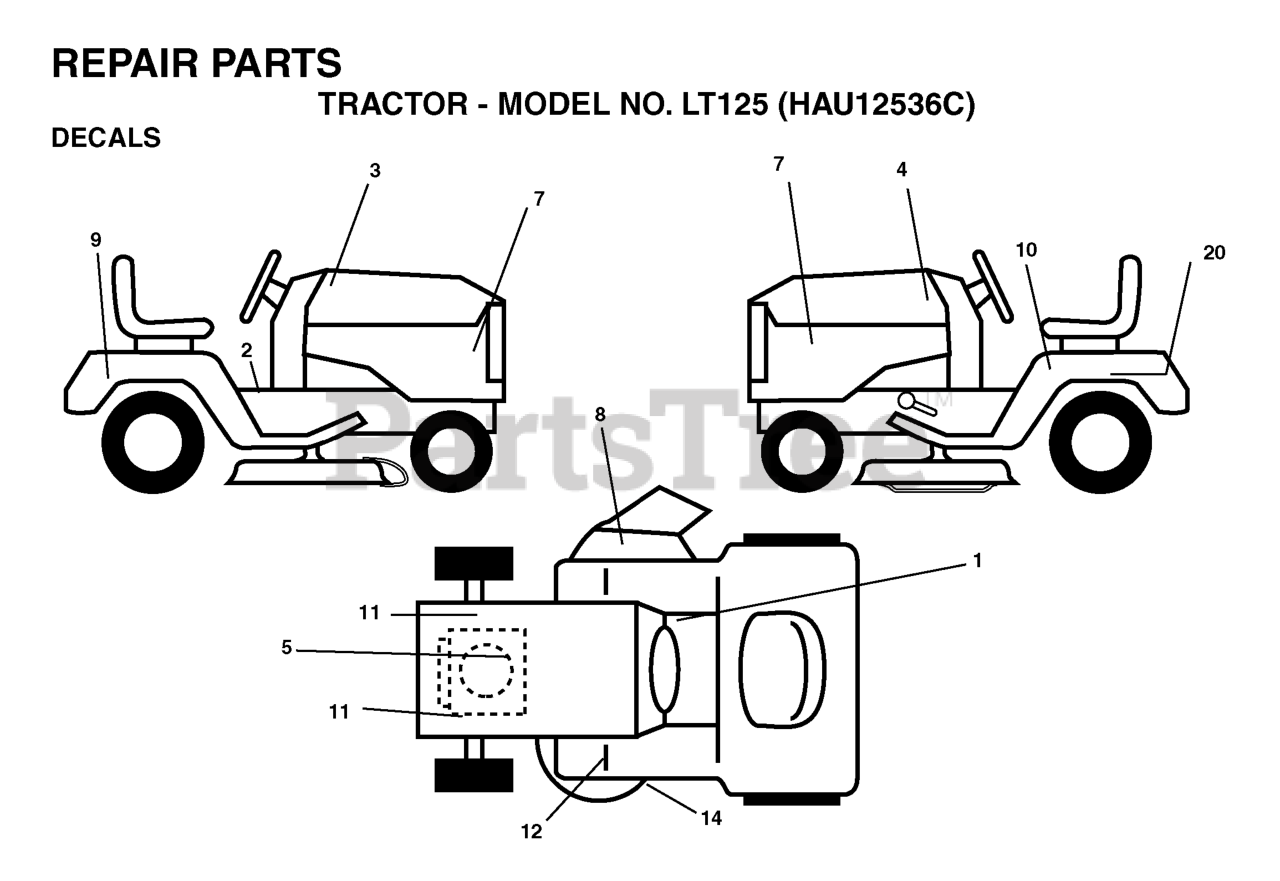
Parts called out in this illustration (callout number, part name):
1	DECAL
2	DECAL PARK BRAKE
7	DECAL PNL SIDE
8	DECAL.INTERNATIONL.CUTFINGER
9	DECAL FENDER HUSQ
10	DECAL READ OWNER'S MAN SYMS
12	DECAL
14	DECAL V-BELT SCHEMATIC
20	DECAL BTRY SYMBOLS
